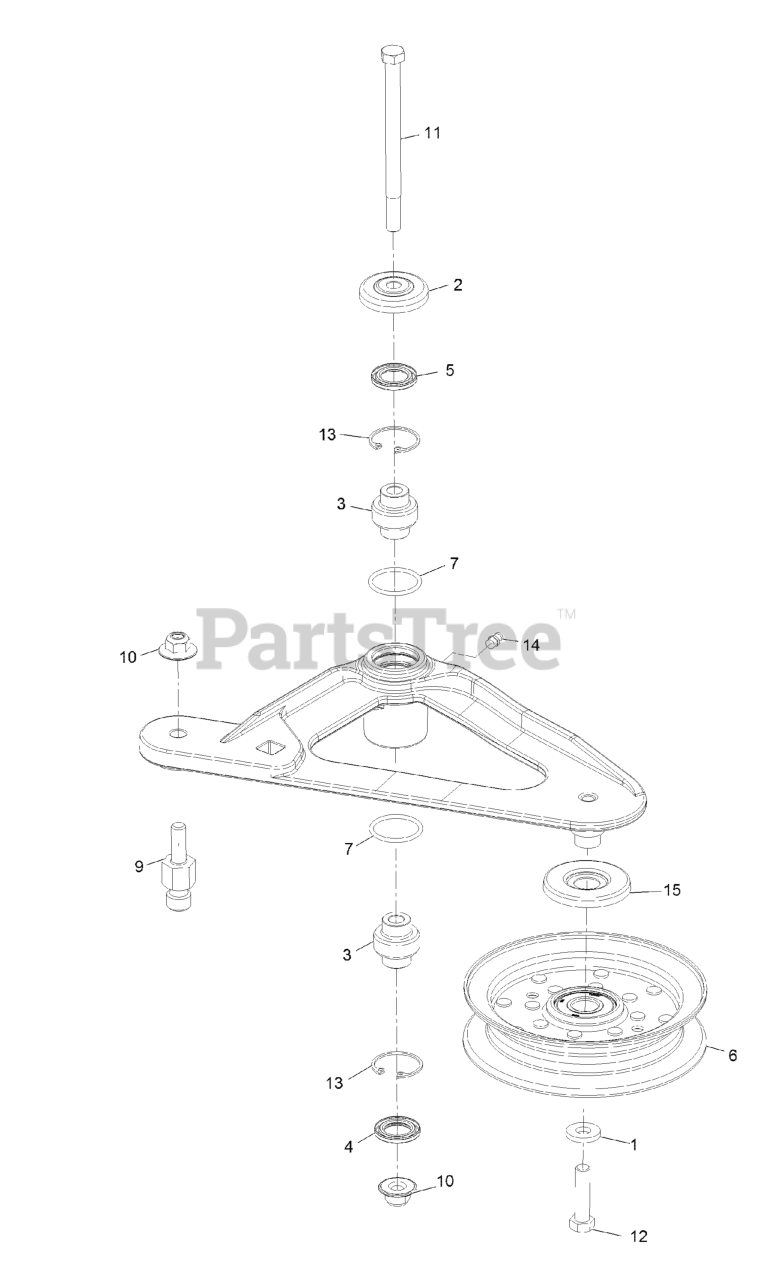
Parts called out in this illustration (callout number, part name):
2	GUARD-TOP
3	BEARING-SPHERICAL
4	SEAL-LIP, DOUBLE
5	SEAL-LIP, SINGLE
6	IDLER-PULLEY, FLAT
9	PIN-SPRING, ANCHOR
10	Nut-Nyloc 3/8-16 Flg
11	SCREW-SHOULDER, HH
12	SCREW-HH
13	RING-SNAP
14	FITTING-GREASE
15	SHIELD-GUARD, DUST
